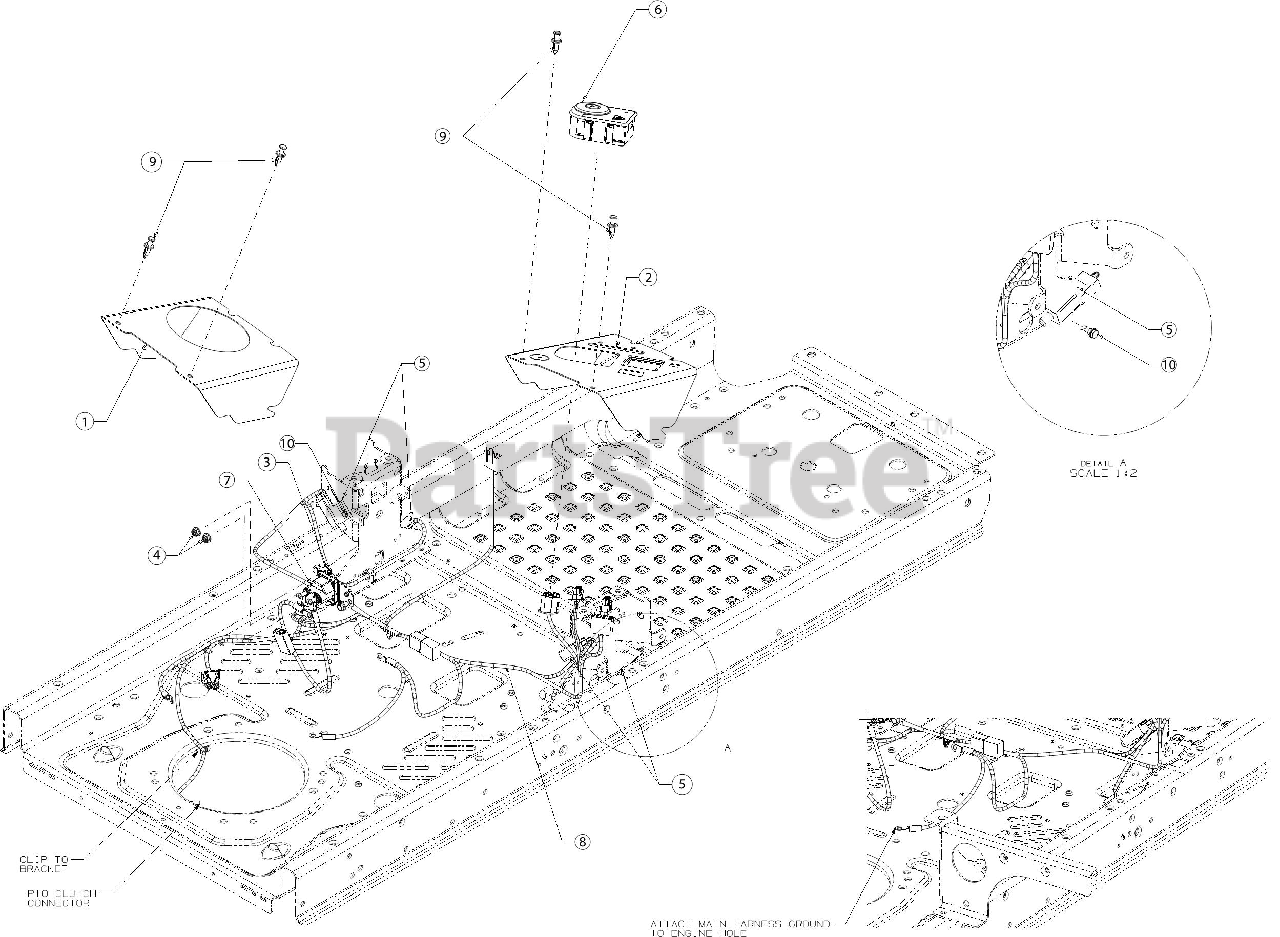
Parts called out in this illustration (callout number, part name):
1	CONSOLE COVER (LH)
2	CONSOLE COVER (RH)
3	SCREW 1/4-20X.625
4	FLANGE LOCK NUT
5	INTERLOCK SWITCH (NO/NC)
6	IGNITION MODULE SWITCH RMC (ELC PTO WHTE)
7	SOLENOID-12V 100A
9	PLASTIC RIVET
10	SHOULDER SCREW
